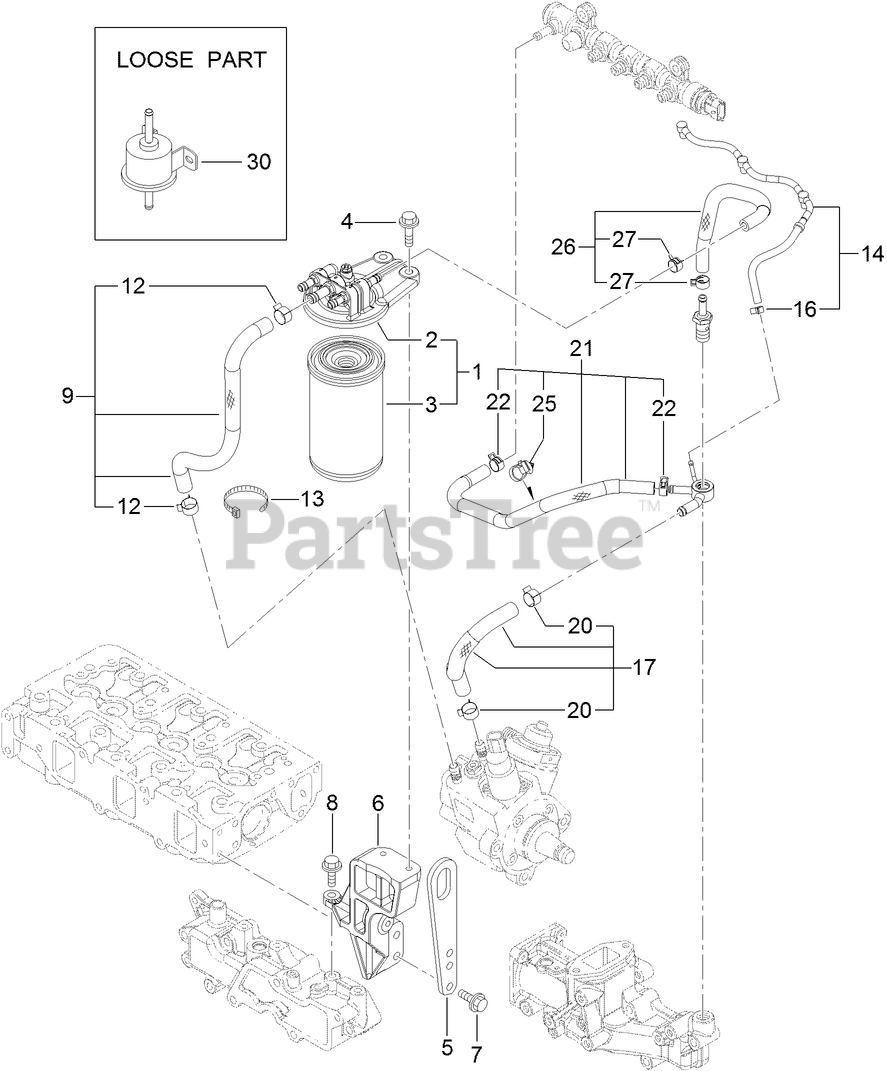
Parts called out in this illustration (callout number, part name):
1	FUEL/OIL FILTER ASM
2	FUEL/OIL FILTER BRACKET ASM
3	FILTER-FUEL/OIL
5	LIFTER
6	FILTER BRACKET ASM
9	FUEL PIPE ASM
12	CLAMP-HOSE
14	FUEL/OIL RETURN PIPE ASM
16	CLAMP-HOSE
17	FUEL PIPE ASM
20	CLAMP-HOSE
21	FUEL PIPE ASM
22	CLIP-HOSE
25	BAND-CLIP
26	FUEL PIPE ASM
27	CLIP-HOSE
30	PUMP-FUEL, ELECTRIC
